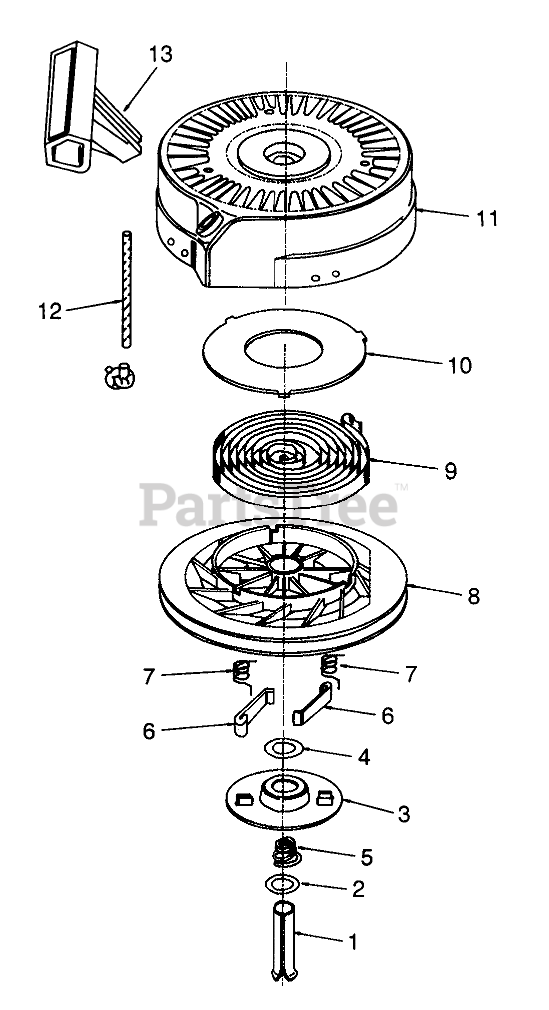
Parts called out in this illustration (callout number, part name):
1	Spring Pin ASM
3	Retainer
5	Brake Spring
6	Dog-Starter
7	Spring-Dog
8	Pulley
9	Rewind Spring
10	Cover-Spring
11	Housing-Starter
12	Rope-Starter (98 cut to length)
13	Handle-Starter
